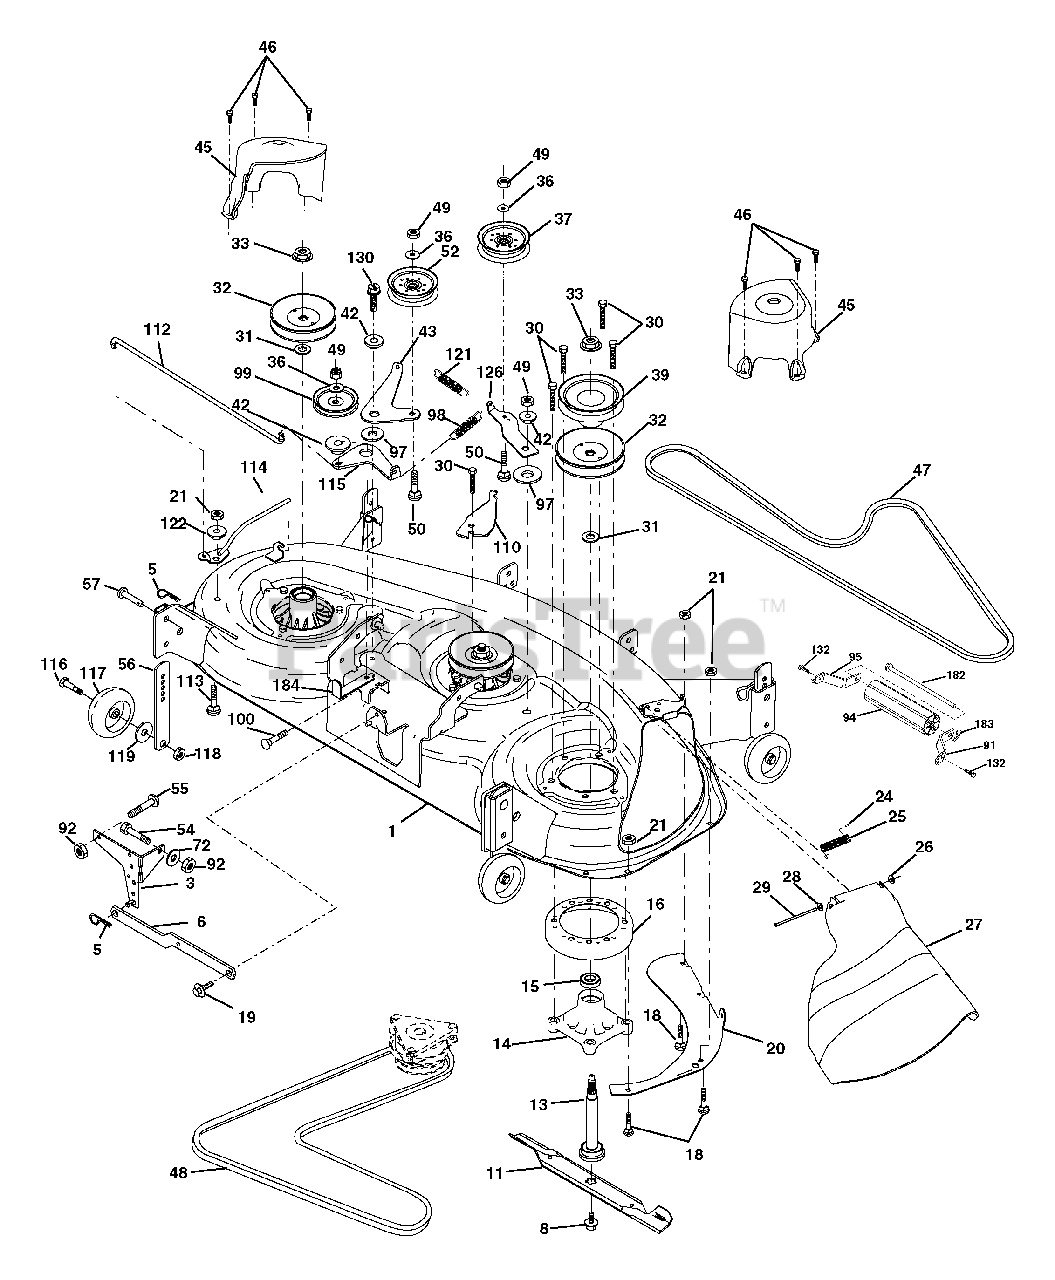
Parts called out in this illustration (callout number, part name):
1	Deck Weldment Mower 48
3	Bracket Asm., Sway Bar
5	Retainer Spring
6	Sway Bar Deck
8	Bolt, 7/16 Asm. Blade
13	Shaft Asm. greaseable
14	Housing Mandrel 48
15	Bearing, Ball, Mandrel
16	Stripper, Mower
17	Bolt Rdhd Sq Neck 3/8-16 x 1.25
18	Bolt, Carriage 5/16-18 x 5/8
19	Bolt, Hex Head, Shoulder 5/16-18
20	Baffle, Vortex Mower
21	Nut, Crownlock 5/16-18 UNC
24	Cap, Sleeve
25	Spring, Torsion
27	Shield, Deflector Mower
28	Washer 11/32 x 5/8 x 16 Ga.
29	Rod, Hinge
30	Screw, Thdroll, Washer Head
31	Washer, Spacer Mower Vented
32	Pulley, Mandrel
33	Nut, Flg. Top Lock Cntr. 9/16
36	Washer 13/32 x 13/16 x 16 Ga.
37	Pulley, Idler, Flat
39	Pulley, Idler, Driven
42	Spacer, Retainer
43	Arm, Idler Secondary
45	Cover, Mandrel Deck
46	Screw, Thdroll. 1/4-20 x 5/8
47	V-Belt, Mower, Secondary
48	V-Belt, Mower, Primary
49	Nut, Crownlock 3/8-16 UNC
50	Bolt, Carriage 3/8-16 x 1-1/2 Gr. 5
52	Pulley Idler Flat 46 Pri. Drive
54	Bolt Fin Hex 3/8-16 x 1
55	Bolt Rdhd Sqnk 3/8-16 x 1
56	Bar Pnt Adjusting Wheel Gauge
57	Pin Head Rivet
72	Washer 13/32 x 13/16 x 12
91	Bracket, Asm Noseroller, LH 48
92	Nut Lock Hex w/Ins 3/8-16
94	Roller, Nose 48
95	Bracket, Asm Noseroller RH 48
97	Washer Hardened
98	Spring Primary Drive
99	Pulley Idler V
100	Bolt RDHD Sqnk 3/8-16 Unc x 2
107	Baffle Vac Edge Mower
110	Arm Spring Secondary
112	Link Tension Relief Lever
113	Bolt Carr. 5/16-18 x 3-4
114	Tension Asm Relief Lever
115	Arm Spring Tension Relief
116	Bolt, Shoulder
117	Gauge Wheel
118	Nut, Centerlock 3/8-16 UNC
119	Washer 3/8 x 7/8 x 14 Ga.
121	Spring Secondary Drive
122	Bushing Pivot Tension Relief
126	Arm, Idler, Primary Deck
130	Screw 3/8-16 x 1.0
132	Screw 3/8-16 x .75
182	Rod Roller Nose
183	Retainer Spring
184	Keeper Belt Idler
